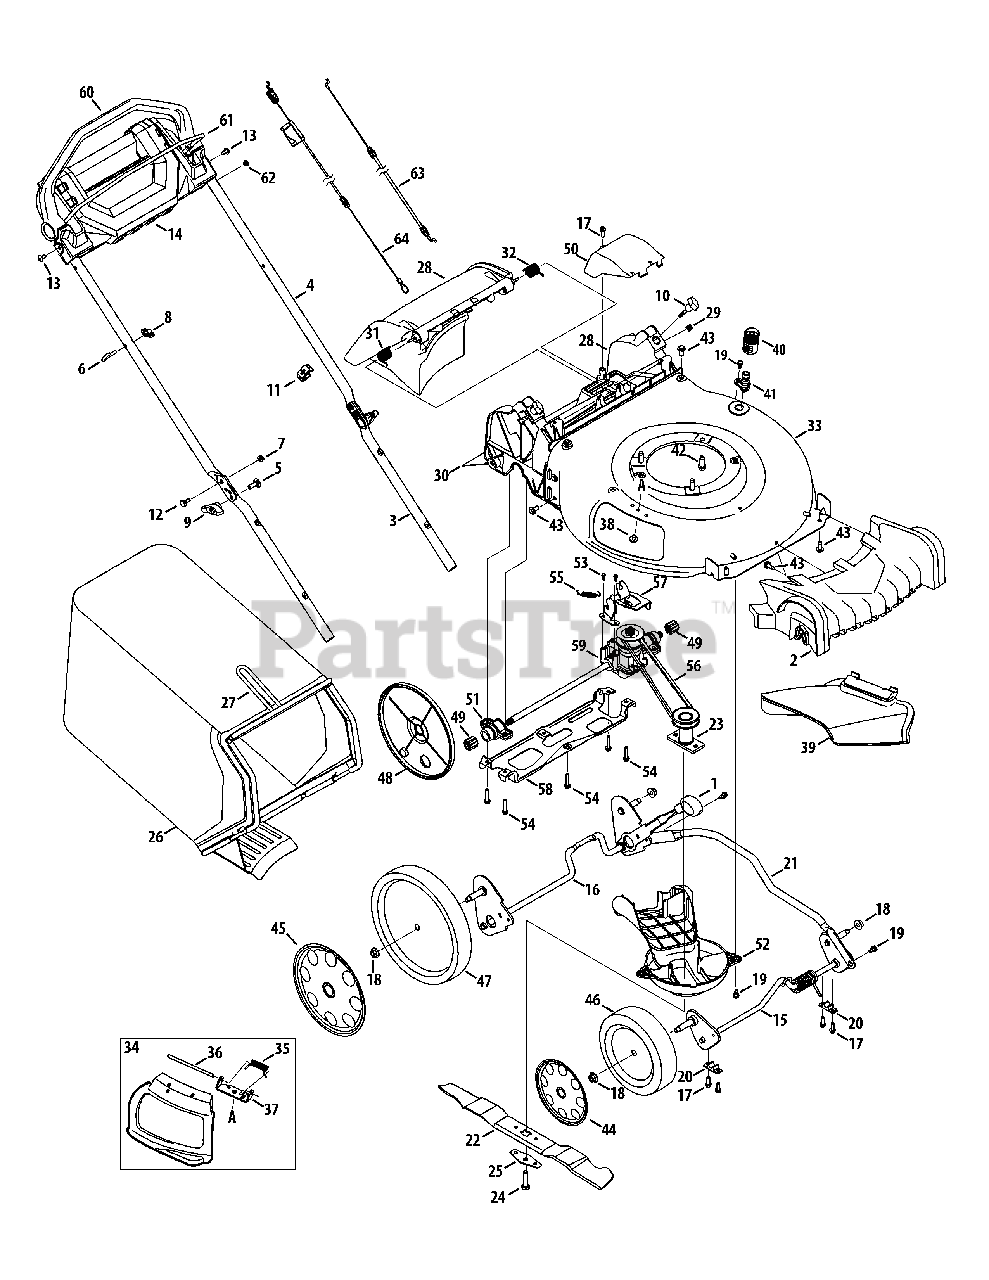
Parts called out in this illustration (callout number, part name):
1	Adjustment Lever Knob
2	Front Cover
3	Lower Handle
4	Upper Handle
5	Carriage Screw ,5/16-18
6	Rope Guide
7	Nut, Flange Lock, 1/4-20
11	Conduit Clip
12	Sldr. Screw, .375 x .126 x 1/4-20
13	Screw, 1/4-14 x .625
14	Handle Console
15	Front Axle Assembly
16	Rear Axle Assembly
17	Screw, 1/4-15 x .750
18	Flange Lock Nut, 3/8-16
19	Shoulder Screw, 1/4-20 x 0.50
20	Bushing, Lock, .505 Dia. X .62
22	Mulching Blade
23	Blade Adapter
24	Screw, 3/8-24 x 1.50
25	Blade Bell Support
27	Grass Catcher Frame
28	Rear Discharge Door Assembly
29	Nut, Sq., 1/4-20
30	Trailing Shield
31	Torsion Spring - RH
32	Torsion Spring - LH
34	Mulch Plug (Incl. 35-37)
35	Torsion Spring
37	Chute Deflector Bracket
38	Screw, 1/4-20 x .500
39	Side Discharge Chute
40	Water Nozzle Adapter
41	Water Nozzle
42	Screw, 3/8-16 x 1.00
43	Screw, 5/16-14 x .750
44	Hubcap, 8"
45	Hubca;p, 11"
46	Front Wheel
47	Rear Wheel
48	Wheel Dust Cover
49	Spur Gear, 9T
50	Transmission Cover
51	Bearing Assembly
52	Engine Baffle
53	Screw, Hex Washer, .159 x .43
54	Screw, 1/4-15 x 1.25
55	Exten. Spring, 2.405
57	Transmission Bracket
58	Rear Support Bracket
59	Transmission Assembly
60	Drive Handle
61	Blade Control
62	Shoulder Spacer, .18 x .315 x .09
63	Control Cable
64	Drive Cable
